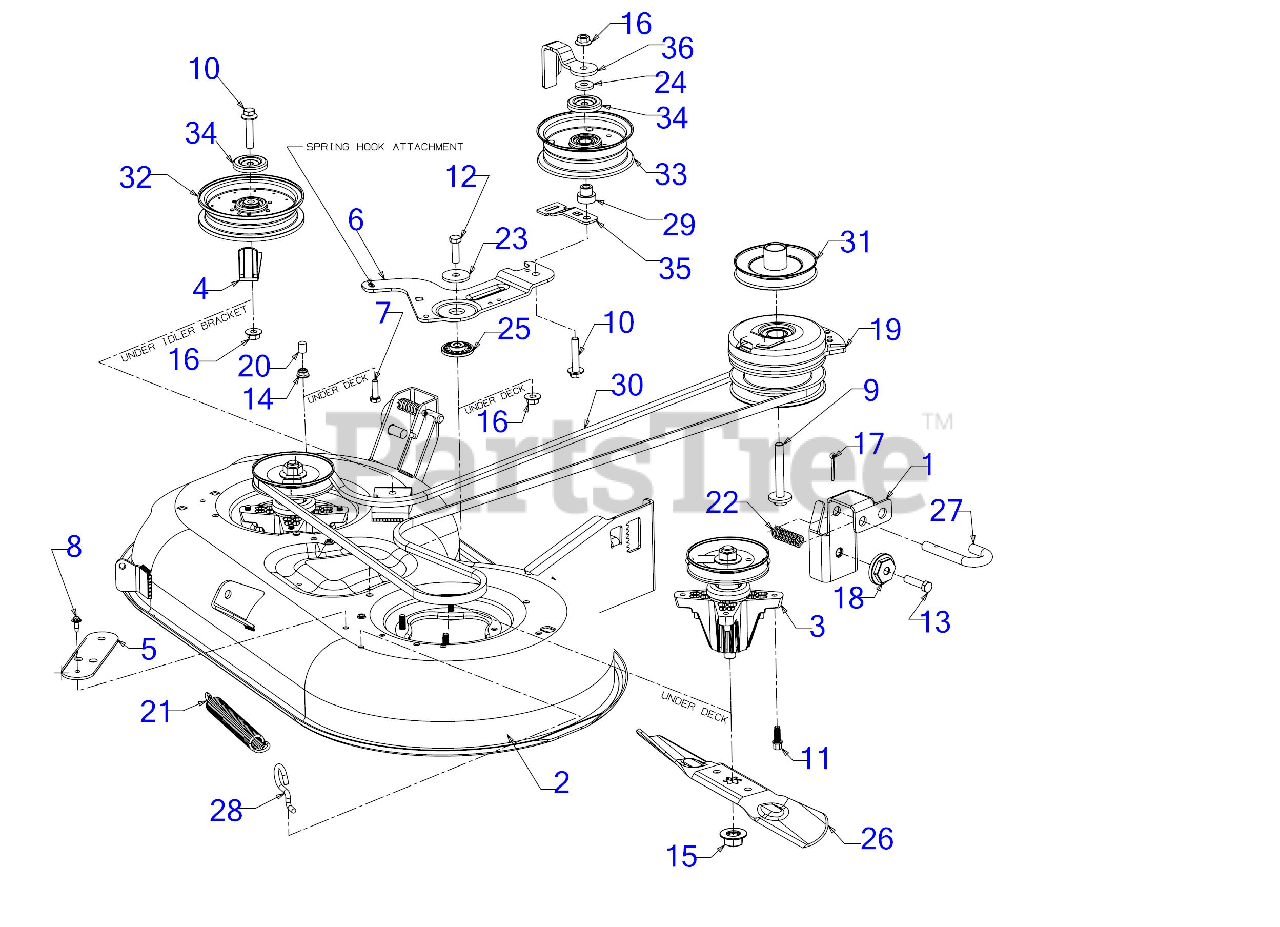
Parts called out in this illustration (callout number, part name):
3	SPINDLE ASSEMBLY
6	IDLER PIVOT BRACKET
7	SCREW 5/16-18 x 1.0 GR5
8	SCREW M6-1 x .625
9	SCREW-SEMS 7/16-20 X 3.25 PATCH
10	SCREW 3/8-16 x 2.0
11	SCREW 5/16-18 X .875
12	SCREW 3/8-16 x 1.25 GR5
13	SCREW 3/8-16X1.5 GR5
14	FLANGE LOCK NUT 5/16-18
16	FLANGE LOCK NUT
17	COTTER PIN-5/32 DIA
18	DECK ADJUSTMENT GEAR
19	ELECTRIC PTO CLUTCH
21	EXTENSION SPRING
22	COMPRESSION SPRING
23	FLAT WASHER .390x1.500x.134
24	FLAT WASHER .385 x 1.00 x .135
25	SHOULDER SPACER
26	17.27" BLADE (2N1)
27	DECK RELEASE PIN
28	DECK SPRING HOOK
29	SHOULDER SPACER
30	V-TYPE BELT A SEC X 111.1
31	TRANSMISSION DRIVE PULLEY
32	FLAT IDLER PULLEY
33	IDLER PULLEY 4.50" DIA
34	IDLER PULLEY CAP
36	IDLER BELT KEEPER
